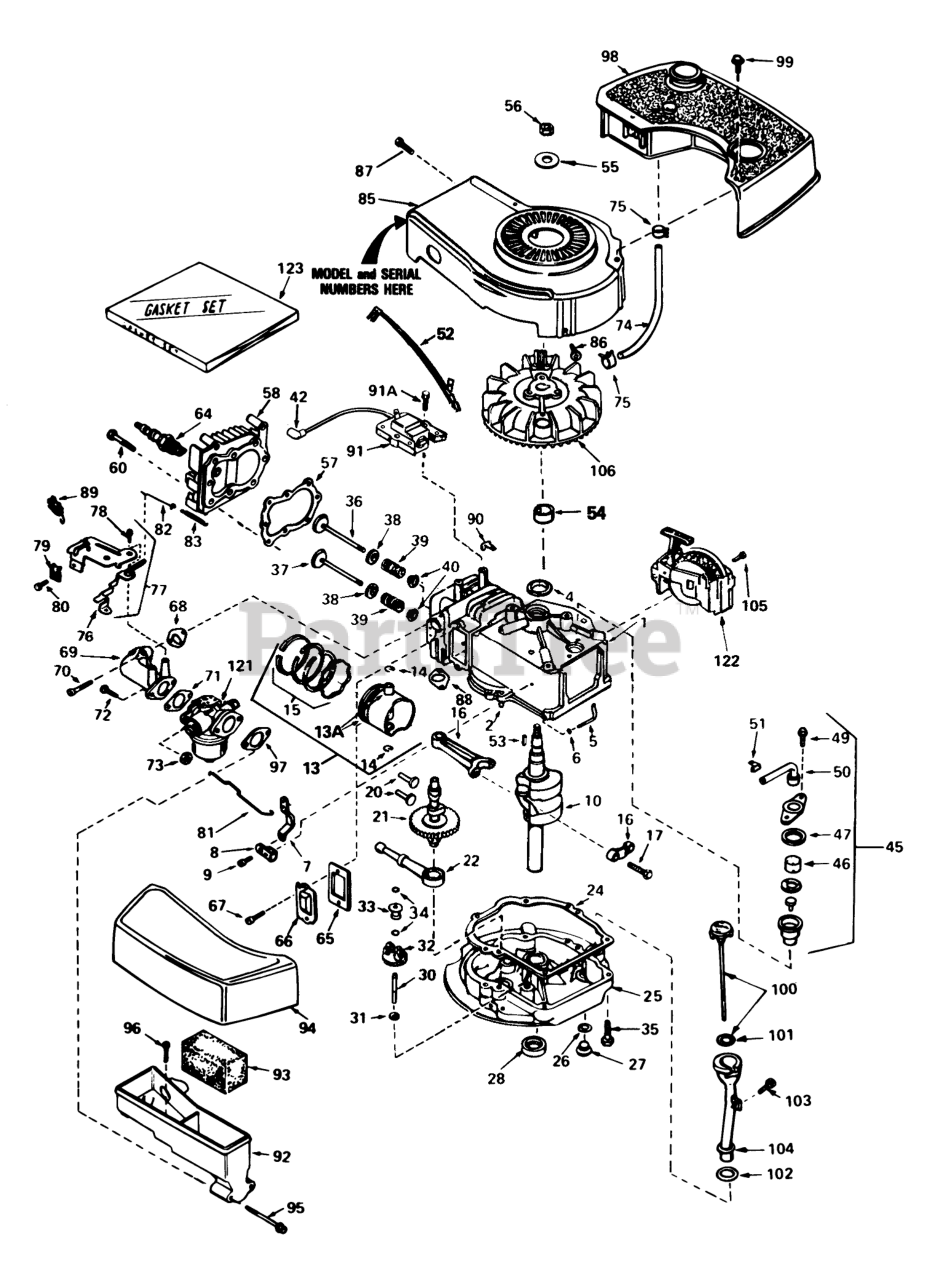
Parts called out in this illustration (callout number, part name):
1	Cylinder Assy. (Incl. Ref. #2 & 4)
2	Pin-Dowel
4	Seal-Oil
5	Rod, Governor (Incl. Ref. #6)
6	Washer-Flat
7	Governor Lever
8	Clamp-Lever, Governor
9	Screw
10	Crankshaft
13	Piston, Pin & Ring Assy. (Std.)(Incl. Ref. #13A, 14 & 15)
13	Piston, Pin & Ring Assy. (.010 oversize)(Incl. Ref. #13A, 14 & 15)
13	Piston, Pin & Ring Assy. (.020 oversize)(Incl. Ref. #13A, 14 & 15)
13A	Piston & Pin Assy. (Std.)(Incl. Ref. #14)
13A	Piston & Pin Assy. (.010 oversize)(Incl. Ref. #14)
13A	Piston & Pin Assy. (.020 oversize)(Incl. Ref. #14)
14	Ring-Retaining, Piston Pin
15	Ring Set (Std.)
15	Ring Set (.020" OS)
15	Ring Set (.010" OS)
16	Rod Assy., Connecting (Incl. Ref. #17)
17	Bolt-Rod, Connecting
20	Lifter-Valve
21	Camshaft(Mech.Comp. Release)
22	Oil Pump ASM
24	Gasket, Mounting
25	Flange Assy., Mounting (Incl. Ref. #26 thru 30)
26	Gasket-Oil Drain
27	Plug Oil Drain
28	Seal Oil
30	Shaft-Governor
31	Washer-Flat
32	Gear Assy., Governor (Incl. Ref. #31)
33	Spool-Governor
34	Ring-Retaining
35	Screw (1/4-20 x 1-1/4)
36	Valve, Intake (Std.)(Incl. Ref. #40)
36	Valve, Intake (1/32" oversize)(Incl. Ref. #40)
37	Valve, Exhaust (Std.)(Incl. Ref. #40)
37	Valve, Exhaust (1/32" oversize)(Incl. Ref. #40)
38	Cap-Upper Valve Spring
39	Spring-Valve
40	Cap-Valve, Spring
42	Cover-Spark Plug
45	Breather Assy. (Incl. Ref. #46 thru 51)
46	Element-Breather
47	Gasket-Breather
49	Screw (10-24 x 9/16)
50	Tube, Breaker
51	Clip, Breather
52	Wire-Ground
53	Key-Flywheel
55	Washer-Belleville
56	Nut-Flywheel
57	63573 GIL 42 SNWTHW
58	Head-Cylinder
60	Screw
64	Plug, Spark (J17LM or equiv.)
64	Plug, Spark (Champion RCJ-8)
65	Gasket-Breather
66	Cover-Valve
68	Gasket-Intake
69	Pipe, Intake (Incl. Ref. #68)
70	Screw (1/4-20 x 1)
71	Gasket-Carburetor
72	Screw (1/4-28 x 7/8)
73	Nut and Lock Washer (1/4-28)
74	Line-Fuel
75	Clamp-Line, Fuel
76	Lever Control
77	Control Assy., Speed (Incl. Ref. #76, 78 & 89)
78	Screw, Hex Washer Hd Shoulder Self-Tap
79	Conduit
80	Screw (10-32 x 3/8)
81	Link-Throttle
82	Link Governor Spring
83	Spring Governor
85	Housing-Blower
86	Screw (1/4-20x19/32)
87	Screw (10-24 x 9/16)
88	Gasket Exhaust
89	Terminal
90	Clip-Wire
91	Lamination & Coil Assy.(Solid State)(Incl. Ref. #42)
91A	Screw
92	Body Air Cleaner
93	Filer, Air
94	Cove, Air Cleaner
95	Screw Fil Hd.
96	Screw, Hex Hd.
97	Gasket-Air Cleaner
98	Tank-Fuel
99	Screw (10-32 x 35/64)
100	Dipstick, Oil (Incl. Ref. #101)
103	Screw (10-32 x 1/2)
104	Tube-Oil Fill
105	Screw (1/2-20x5/8)
106	Flywheel
121	Carburetor (Incl. Ref. #71)
122	Starter-Sidemount
123	Gasket Set (Incl. Items Marked )
